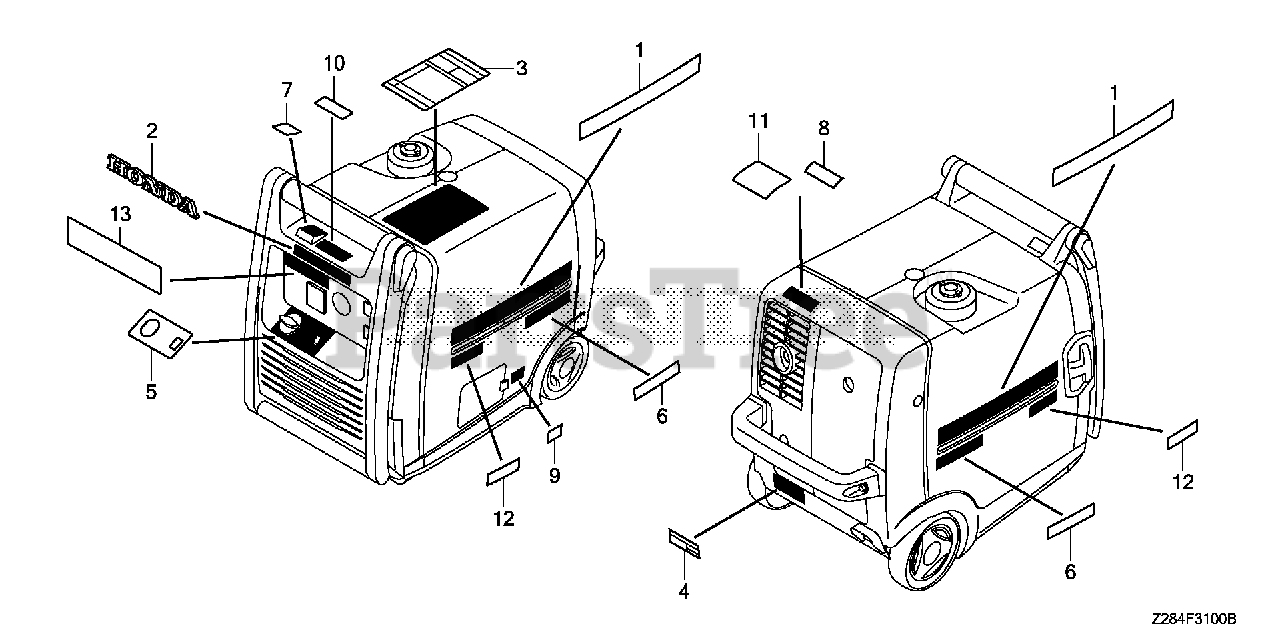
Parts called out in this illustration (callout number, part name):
1	MARK, EMBLEM (EU3000I)
2	MARK, HONDA
3	MARK, CAUTION
4	MARK, SPEC
5	MARK, ENGINE SWITCH
6	MARK, HONDA
7	MARK, INDICATOR
8	MARK, EX. CAUTION
9	MARK, OIL CAUTION
